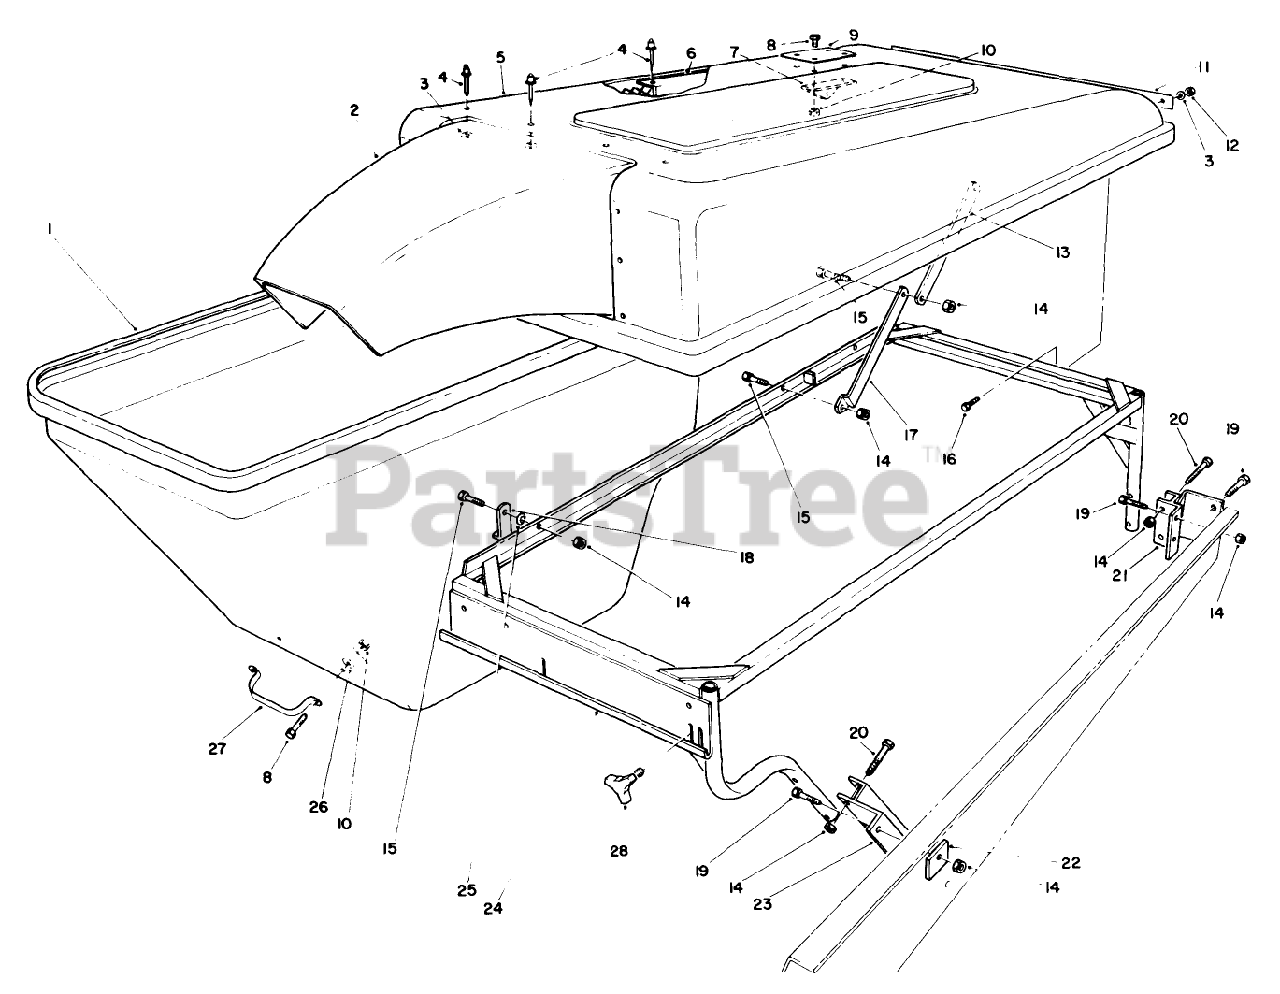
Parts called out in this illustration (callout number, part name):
1	BAGGER HOPPER
2	BAGGER SNOUT
3	WASHER-FLAT
4	RIVET-POP
5	Hood-Bagger
6	Bagger Screen
7	Pivot
8	SCREW-HH
9	HOOD PLATE
10	NUT-LOCK, NI
11	HINGE PLATE
12	NUT-LOCK, NI
13	Link
14	NUT-LOCK, NI
15	SCREW-HH
17	Link-Bag
18	Latch-Hopper
19	SCREW-HH
20	SCREW-HH
21	Bracket-Rear
22	Plate-Reinforcing
23	Bracket-Front
24	HOPPER FRAME WA
25	WASHER-SPRING
26	WASHER-FLAT
27	Handle
